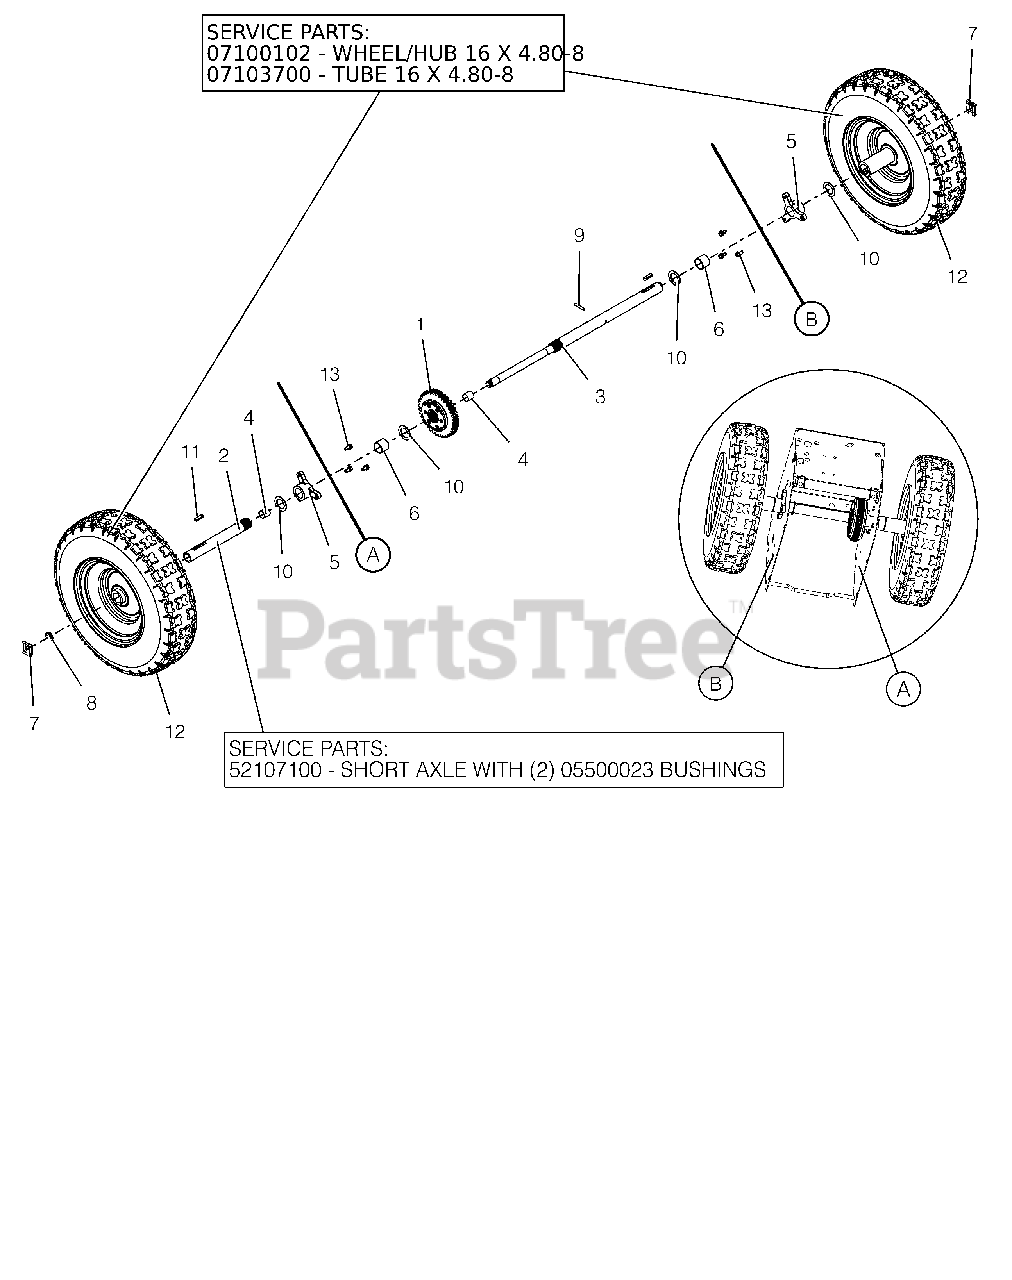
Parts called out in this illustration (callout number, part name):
1	DIFFERENTIAL, AUTOMATIC
2	KIT, SHORT AXLE W/BUSHINGS
2	BSHG-SLV .706X.764X.75 BRZ
3	AXLE, LONG - DIFFERENTIAL
4	BSHG-SLV .706X.764X.75 BRZ
5	BUSHING, AXLE
6	BSHG-SLV, 1.012X1.125X.875
7	CLIP, SNAP .625 DIA
8	RG-RTNG-EXT .625X.042
9	PIN-ROLL .188X1.25
10	WSHR-FL-STL 1.010X1.505X.062YZ
11	KEY-RECT .25X.188X1.00
12	TIRE/WHEEL,16X4.80-8 POLAR TRK
12	HUB, WHEEL - 16X4.8-8 DIFF
12	TUBE
13	SCR-TAP .25-20X.50 HWH TR YWZ
